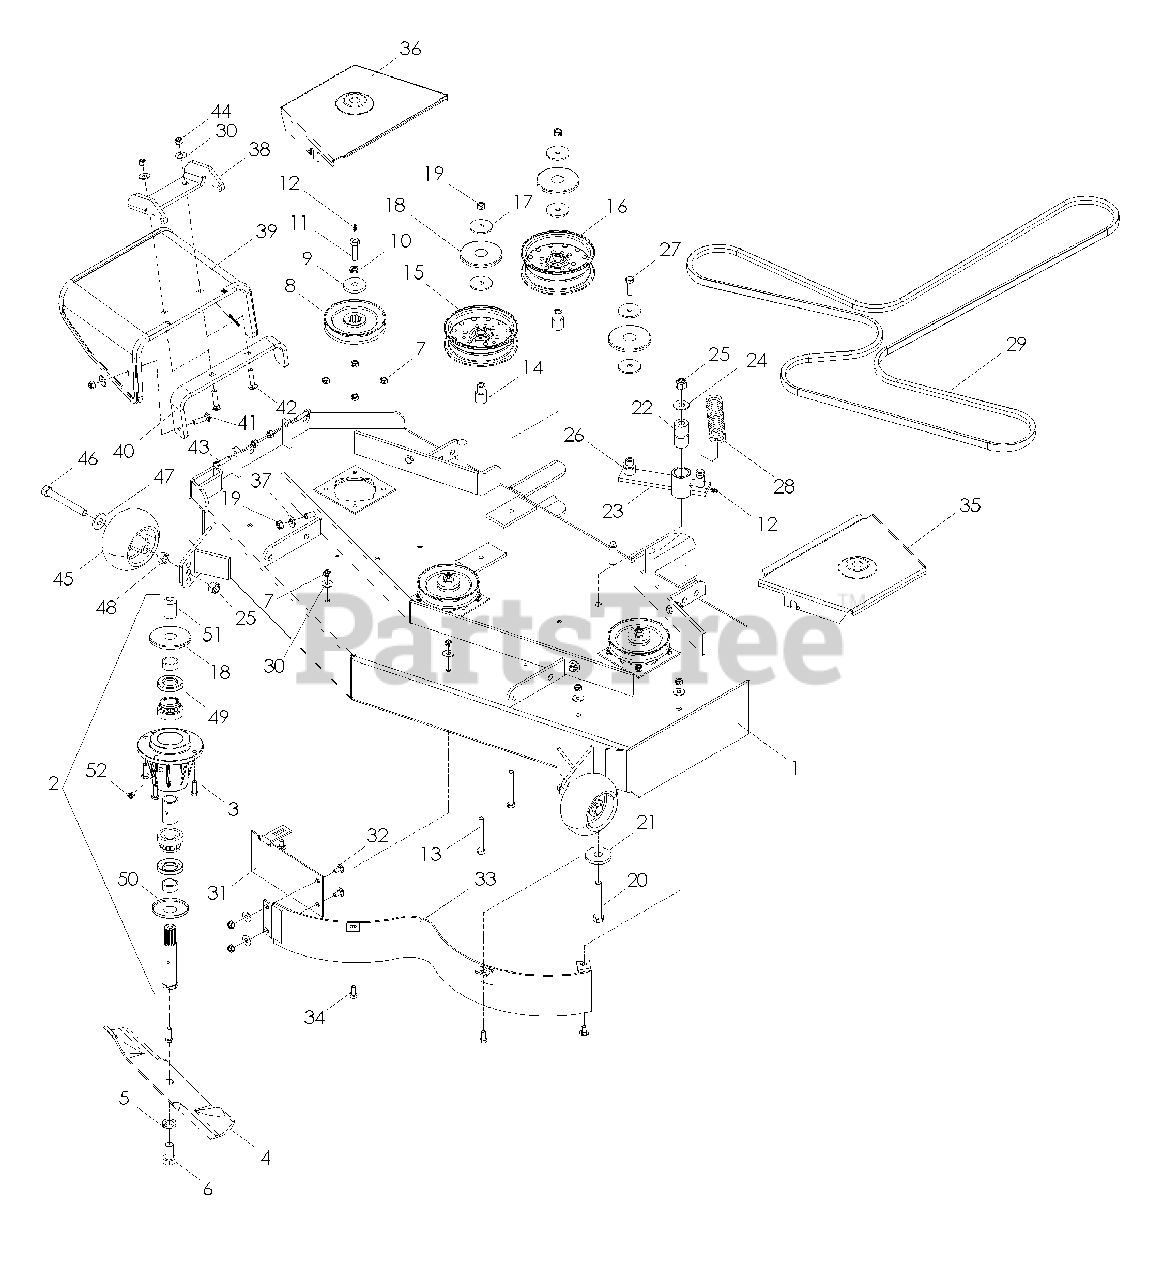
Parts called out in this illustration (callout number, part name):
1	DECK W/DECALS
2	SPINDLE ASM
3	HCS 5/16-18 x 1
4	BLADE 16 1/4
5	WASHER 5/8 SLW
6	HCS 5/8-18 x 1 1/4
7	NUT 5/16-18 HEX CTRLK
9	WASHER, HEAVY
10	WASHER 7/16 SLW
11	HCS 7/16-20 x 1 1/2 GR8 SPEC
12	ZERK
13	HCS 3/8-16 x 3
14	BUSHING, IDLER
15	PULLEY, IDLER
16	PULLEY, IDLER
17	WASHER 3/8 SPECIAL
18	TOP DUST CAP
19	NUT 3/8-16 HEX CNTRLK
20	HCS 1/2-13 x 3 1/4
21	WASHER, SUPPORT
22	BUSHING, PIVOT
23	ARM, IDLER
24	WASHER 1/2 STD FLT
25	NUT 1/2-13 HEX NYLOC
26	BUSHING 5/8 MACHINERY
27	HCS 3/8-16 x 1 1/4
29	BELT, DECK
30	WASHER 5/16 STD FLT
31	BAFFLE, CENTER
32	RHSNB 5/16-18 x 5/8
33	BAFFLE, MAIN
34	HCS 5/16-18 x 3/4
35	SHIELD, LT
36	SHIELD, RT
37	WASHER 3/8 FLAT
38	BRACKET, PIVOT
39	CHUTE, RUBBER
40	REINFORCEMENT, BRACKT
41	RHSNB 5/16-18 x 1 1/4
42	RHSNB 5/16-18 x 1 1/2
43	HCS 5/16-18 x 1 1/4
44	NUT 5/16-18 HEX NYLOC
45	WHEEL, GAUGE
46	HCS 1/2-13 x 4
47	WASHER 1/2 FLAT
48	NUT 1/2-13 HEX
49	SEAL, SHAFT
50	DUST CAP, BOTTOM
51	CAP, VINYL
52	GREASE POPPET
